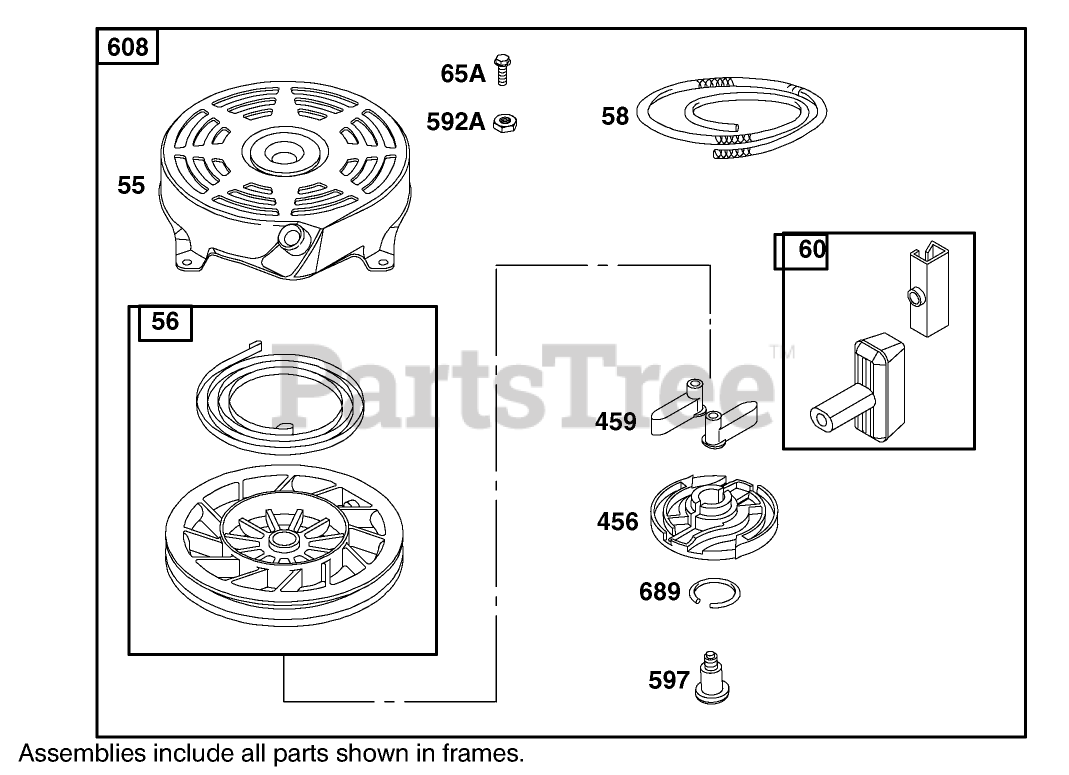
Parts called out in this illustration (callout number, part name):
56	PULLEY-STARTER, REWIND
58	ROPE-STARTER
65A	SCREW-HH
456	RETAINER-STARTER, REWIND
459	PAWL-STARTER
592A	NUT-HEX
608	REWIND ASM
689	SPRING-TORSION
